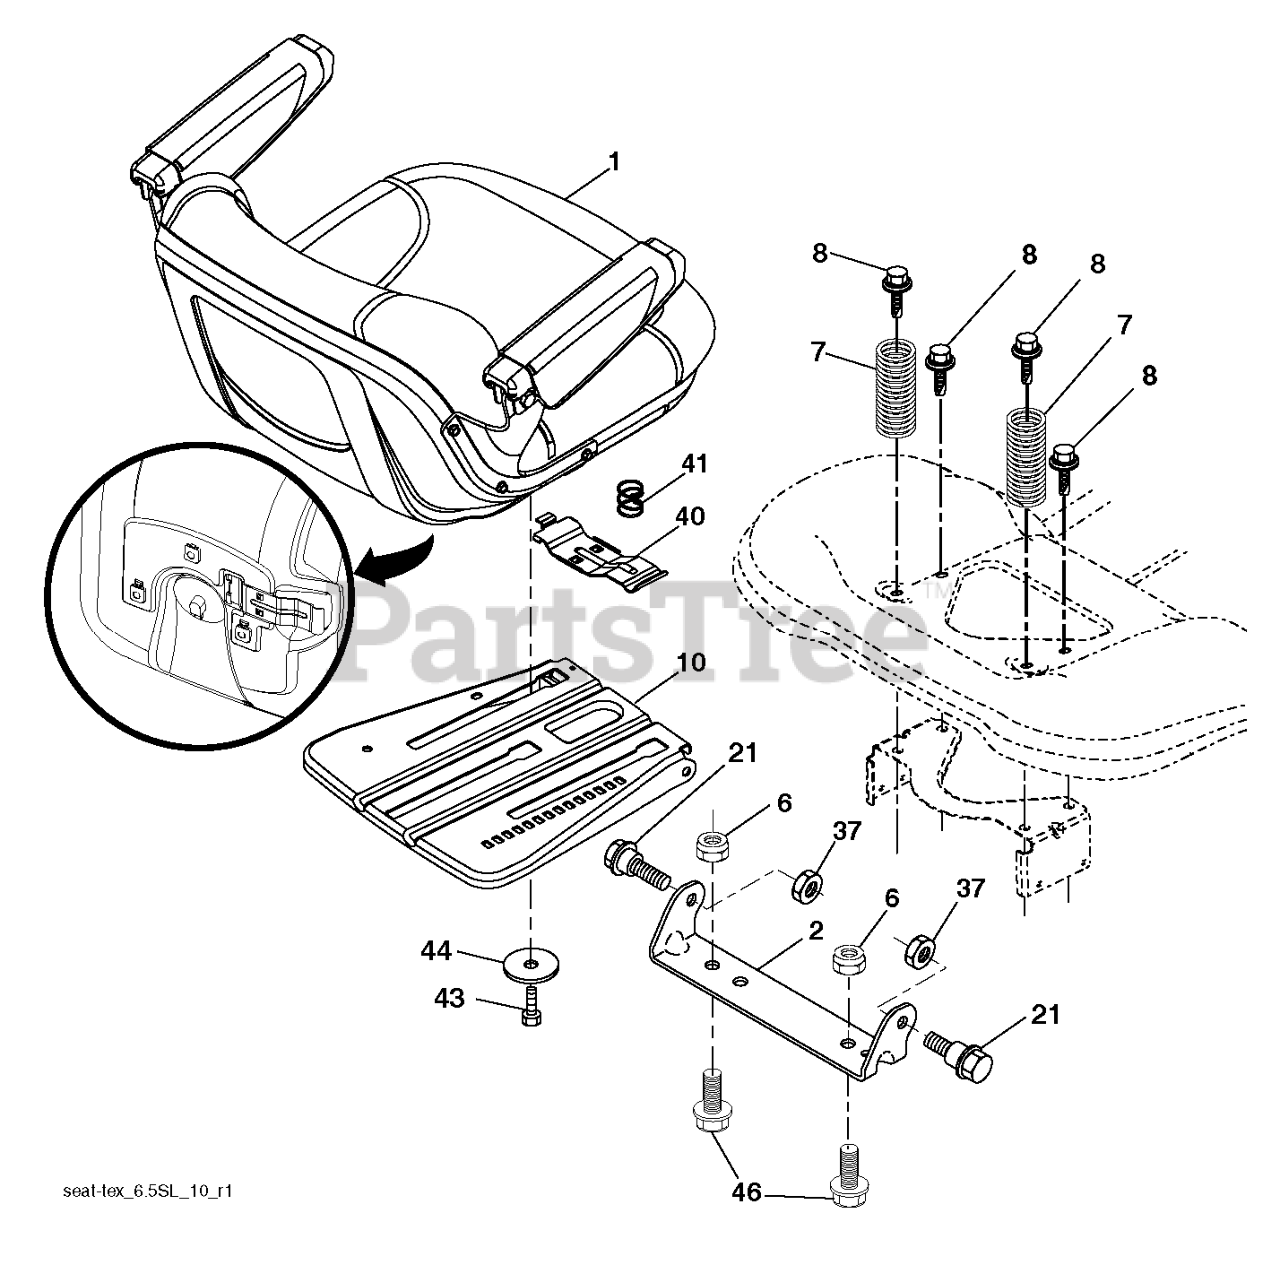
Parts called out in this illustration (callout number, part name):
1	SEAT.TH154.GREY.HUS.ARMREST
2	BRKT.PIVOT.FENDER
6	NUT
7	SPRING.COMPRESS.SEAT.TAPERED
8	BOLT.5/16-18UNCX3/4 W/SEMS.BLK
10	PAN.ASM.SEAT.3PT
21	BOLT.5/16-18X5/8.SHOULDER
37	NUT.71038.31-18.HEX.NYLOCK
40	HANDLE.SLIDE.SEAT.TEX.BLACK
41	SPRING.LATCH.SEAT.TEX
44	WASHER 13/32 X 2-3/8 X 12GA
46	BOLT.3/8-16X1;1.25OD.WSHR.SEMS
